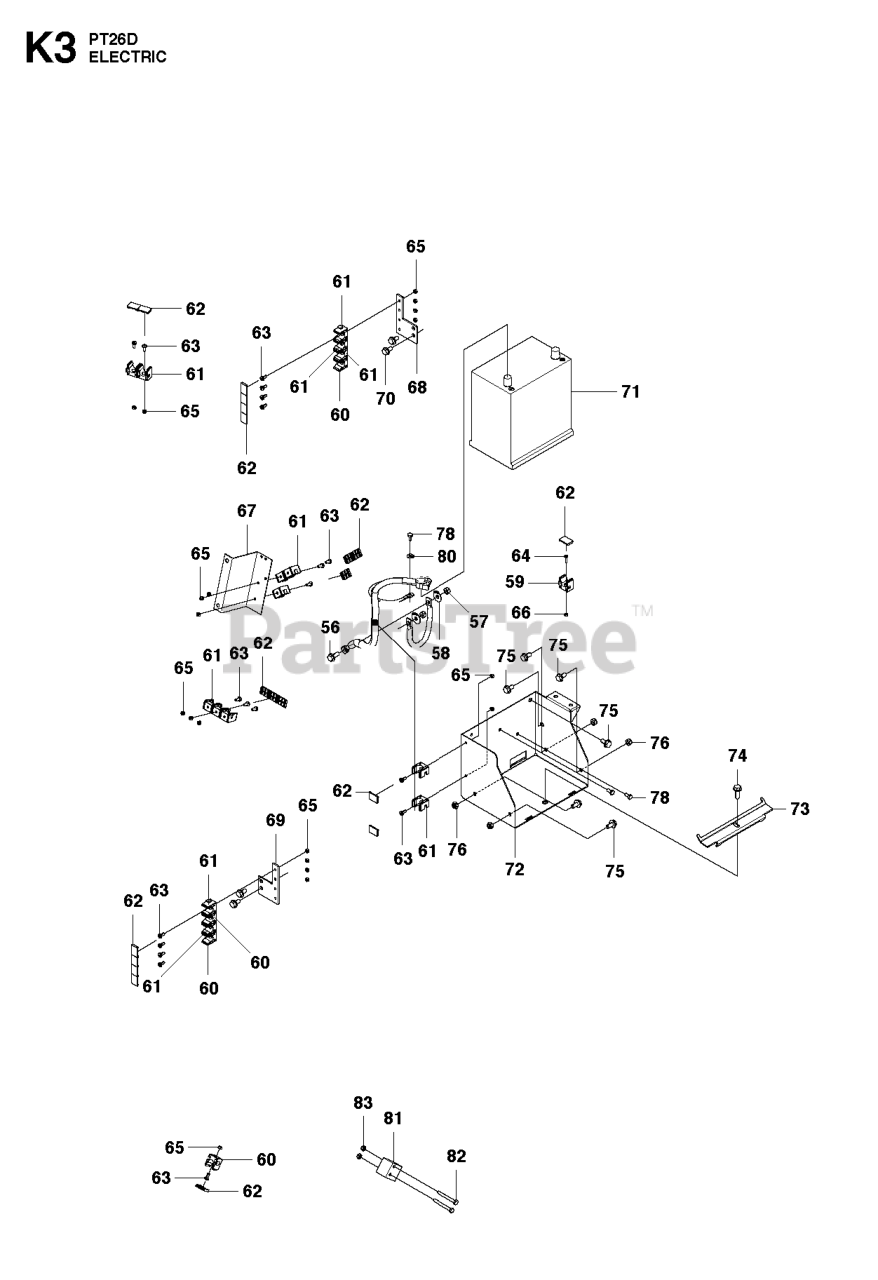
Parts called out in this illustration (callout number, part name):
57	LOCKNUT M8
58	WASHER BRB 8.4X17
65	LOCKNUT M5
74	BOLT
76	LOCKNUT M8
80	WASHER
81	BRACKET SENSOR LIFT
82	SCREW M6X55
83	LOCKNUT M6
